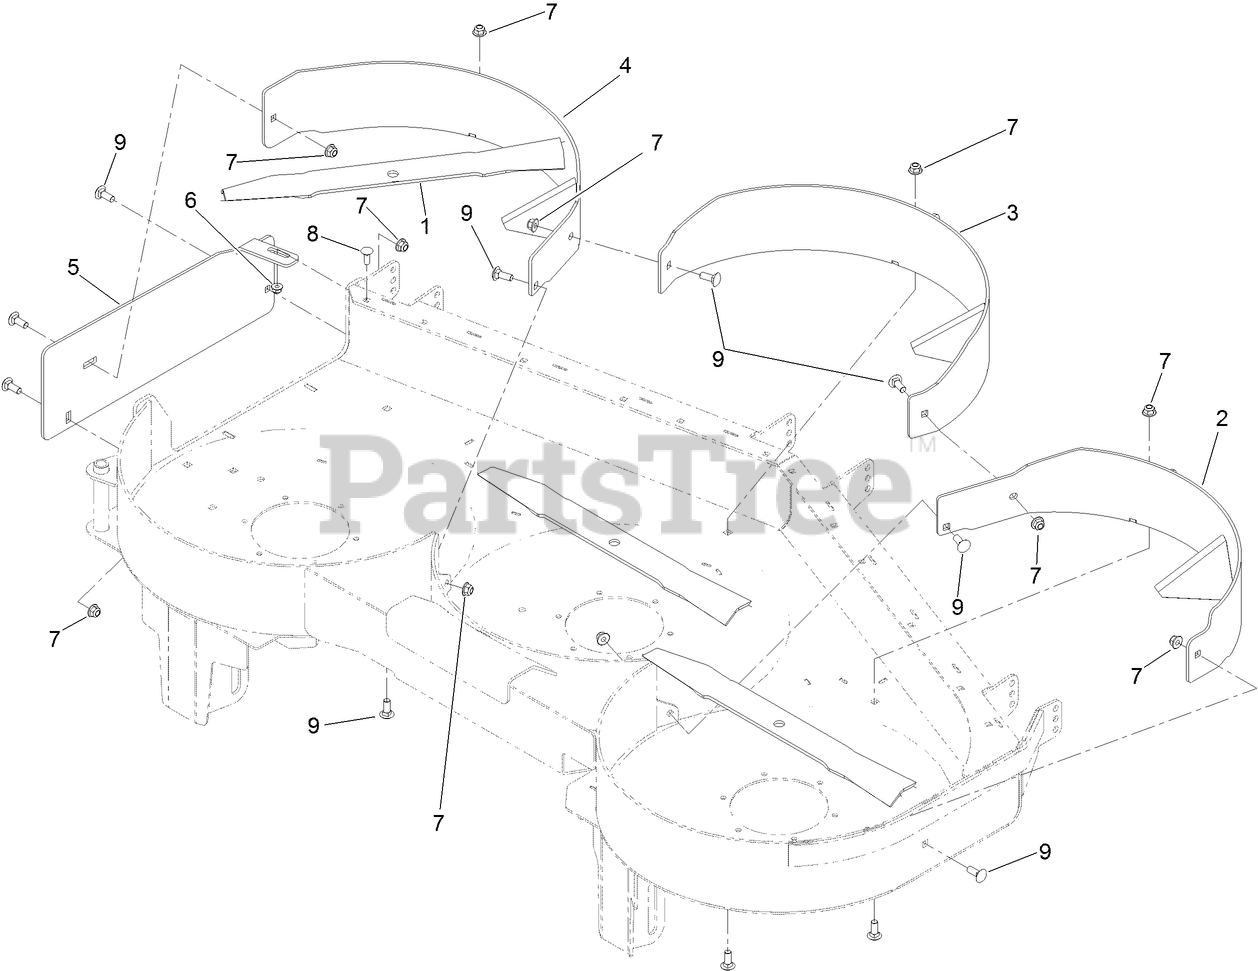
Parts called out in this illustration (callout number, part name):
1	BLADE-MULCH, 20.50 INCH
2	BAFFLE-LH
3	BAFFLE-CENTER
4	BAFFLE-RH
5	PLATE-COVER, DISCHARGE
6	NUT-HF, NI
7	NUT-HF, NI
8	SCREW-CARR
9	BOLT-CARR
